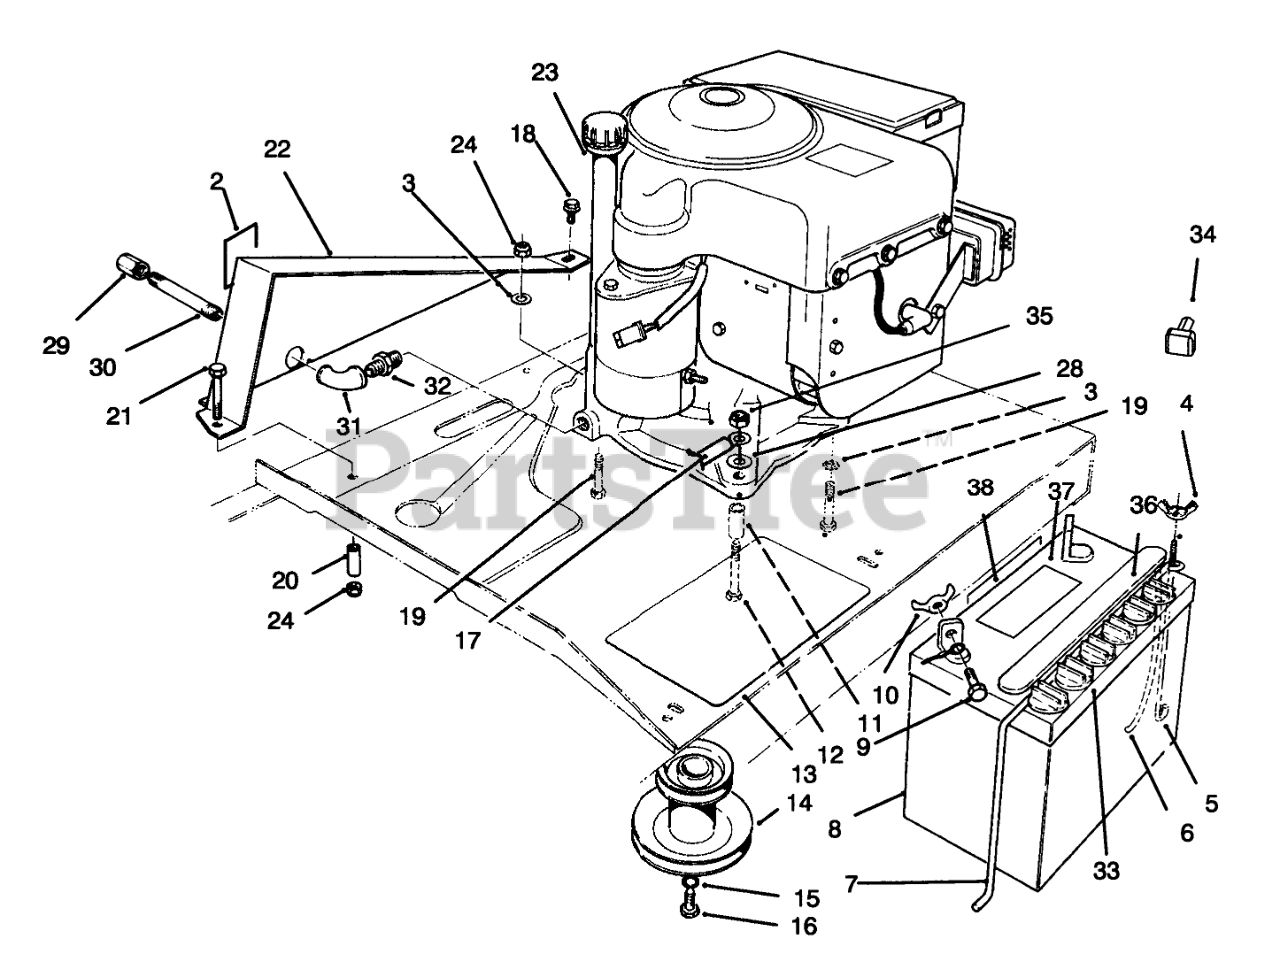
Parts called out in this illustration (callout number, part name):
3	WASHER-PLAIN
4	NUT-WING
5	POST-BATTERY
6	TUBE-BATT DRAIN/80-2600
7	HOLDDOWN-BATTERY
8	Battery
9	SCREW-HH
10	NUT-WING
11	SPACER-PIVOT
12	SCREW-HH
13	PAD-SKID, ANTI
14	Pulley-Engine
15	WASHER-FLAT
16	SCREW-HH
17	WIRE ASM
18	SCREW-HWHTF
19	SCREW-HH
20	GUIDE-BELT
21	SCREW-HH
22	GUIDE-CHAIN
23	Engine-8 H.P. B & S
24	NUT-LOCK, NI
28	WASHER-LOCK
29	CAP-PIPE
30	NIPPLE-PIPE
31	ELBOW-STREET
32	BUSHING-PIPE
33	CAP-BATTERY
34	BOOT-TERMINAL
35	NUT-HEX, SIDE DEFORM
36	DECAL - DANGER
37	DECAL-DANGER
38	DECAL-BATTERY
